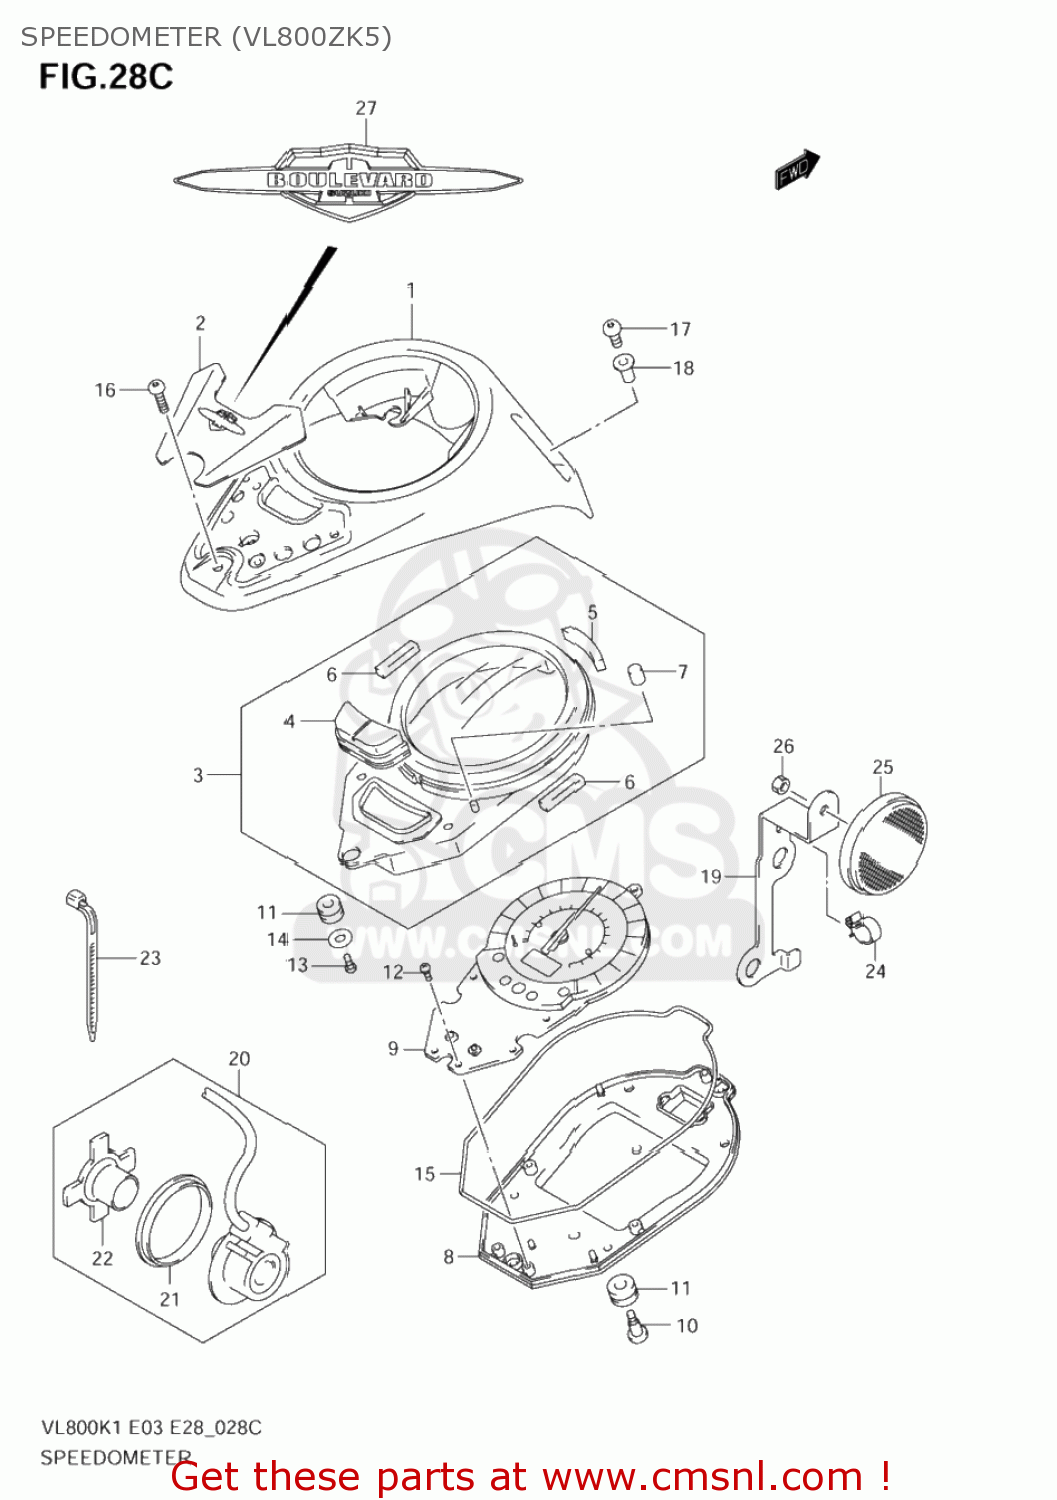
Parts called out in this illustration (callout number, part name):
1	CASE ASSY
2	PLATE,DECORATION
3	CASE,UPR
4	SWITCH,SELECT
5	CUSHION NO.1
6	CUSHION NO.2
7	CUSHION NO.4
8	CASE,LWR
9	SPEEDOMETER
10	BOLT
11	CUSHION,METER
12	SCREW(3X10)
13	SCREW(4X14)
14	WASHER
15	GASKET,METER CASE (NAS)
16	SCREW(5X14)
17	SCREW(5X18)
18	NUT
19	GUIDE,SPEED SENSOR LEAD
20	SENSOR,SPEED
21	SEAL,OIL(44X55X6)
22	MAGNETO
23	CLAMP(L:145)
24	CLAMP
25	REFLECTOR,REFLEX FR
26	NUT
27	EMBLEM,BOULEVARD
